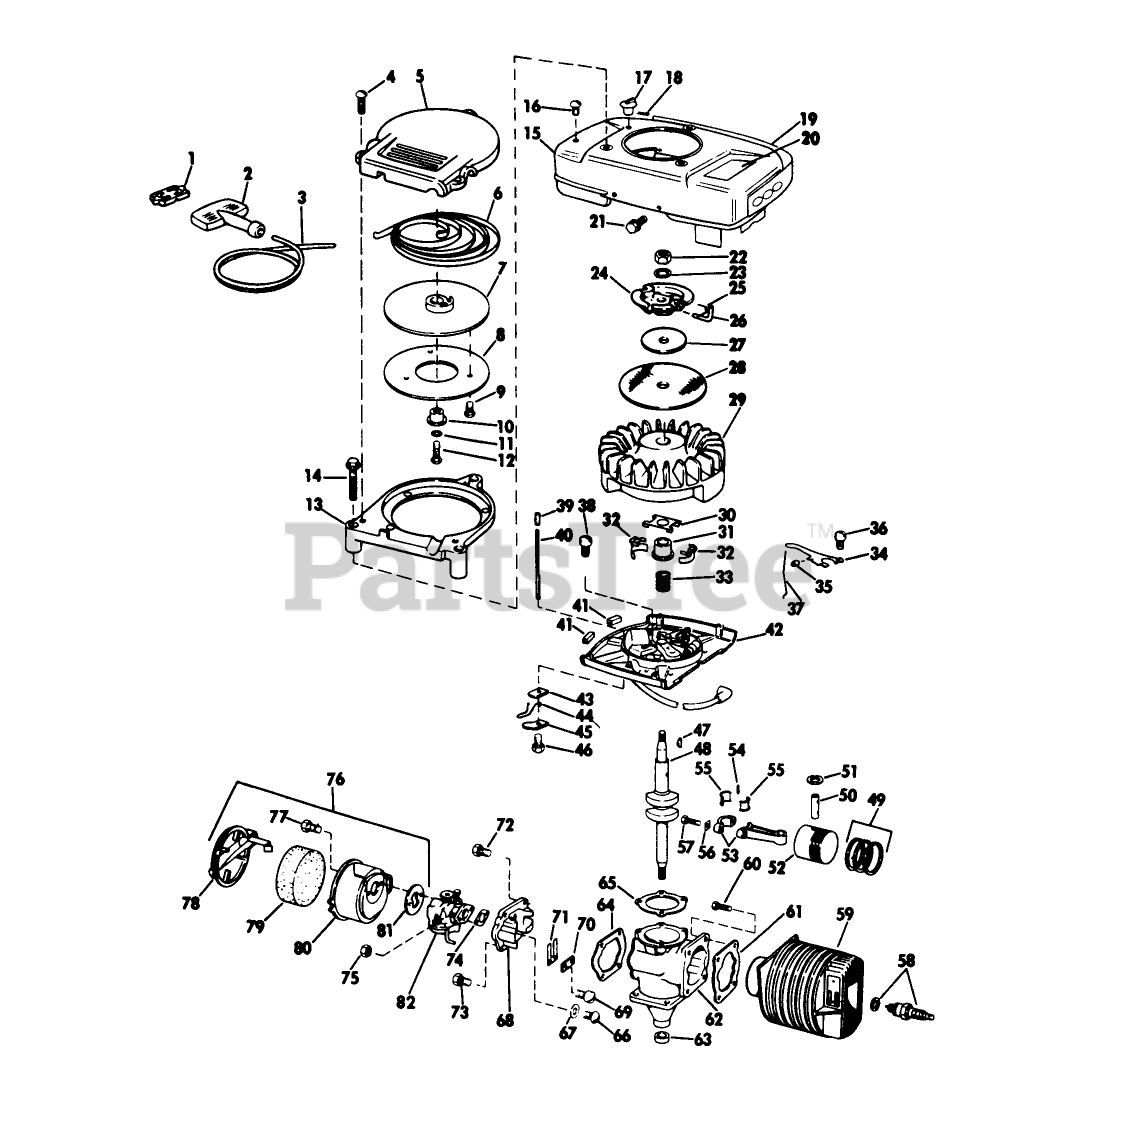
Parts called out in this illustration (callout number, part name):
6	RECOIL SPRING
17	KNOB, CHOKE BAR
18	Cotter Pin-Choke Knob
21	SCREW S
26	PIN - STARTER
31	COLLAR S
34	GOVERNER LEVER AY
35	WEAR BLOCK S
37	GOVERNOR ROD S
46	Screw Shut-off Switch
51	RING-RETAINING
55	LINER ASM
61	GASKET S
65	GASKET S
70	PLATE-BACKUP, REED
72	SCREW S
73	SCREW S
74	GASKET S
75	STOP NUT
77	SCREW S
79	AIR FIL.ELEM S
81	GASKET S
